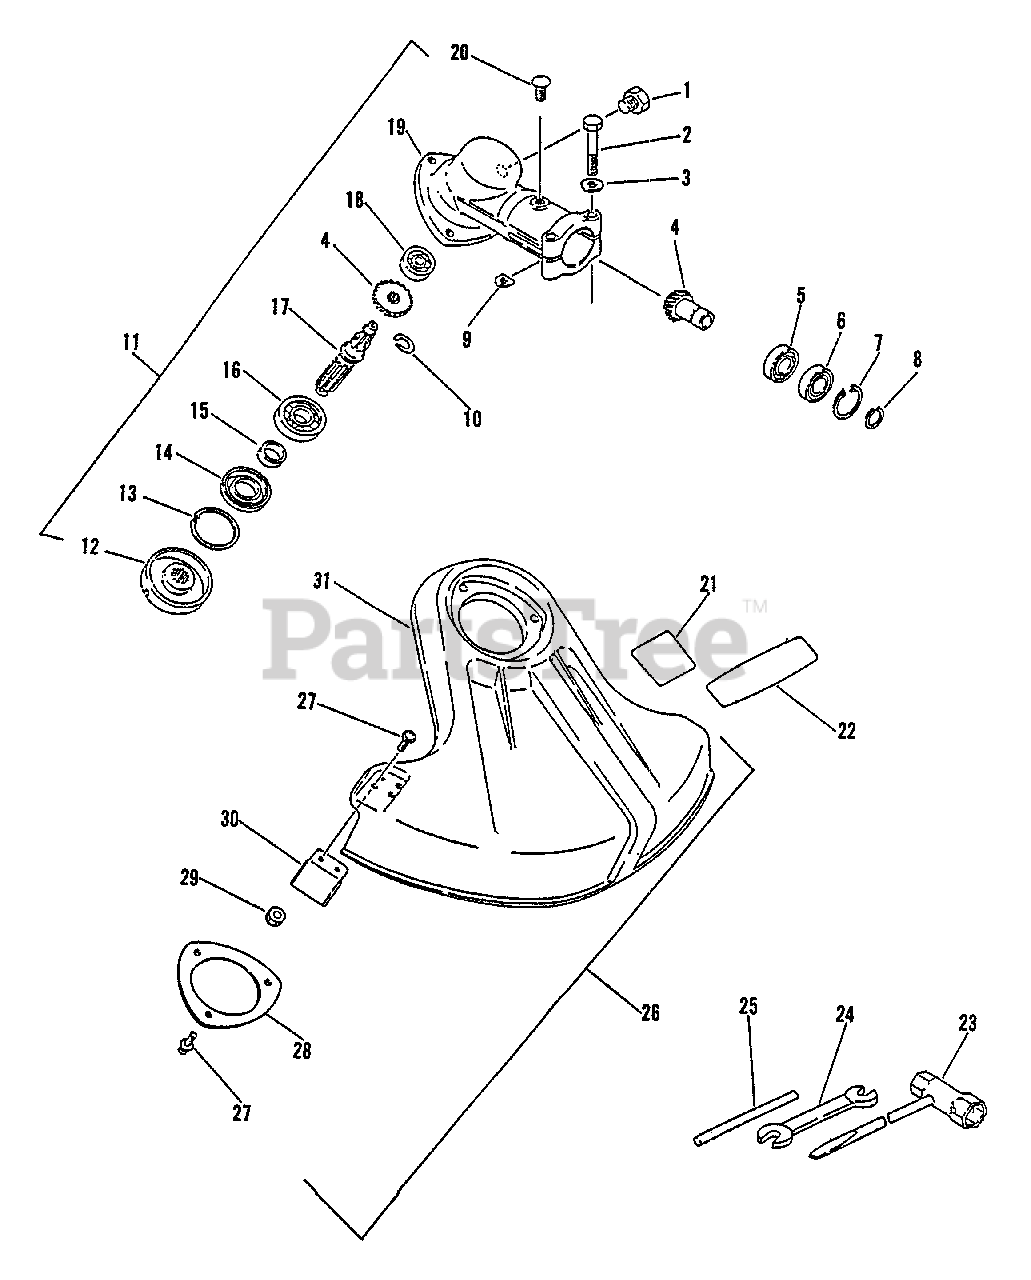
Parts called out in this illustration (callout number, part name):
1	Bolt 8X8
2	Bolt 5X35
3	Washer 5
4	Gear Set, Bevel
5	Bearing, Ball 6900
6	Bearing, Ball 6900
7	Circlip 22
8	Circlip 12
9	Washer Shim
10	Circlip 10
11	Housing Asy, Gear
12	Plate, Adapter (U)
13	Circlip 32
16	Bearing, Ball 6201
17	Shaft, P.T.O.
18	Bearing, Ball 609
19	Housing, Gear
20	Screw 5X10
21	Label, Caution
22	Label, Echo
23	Wrench, W\Screwdriver
24	Spanner 8X10
25	Locking Tool
26	Shield Asy
27	Screw 5X16
28	Brakcet, Shield
30	Knife, Cord
31	Shield, Blade
